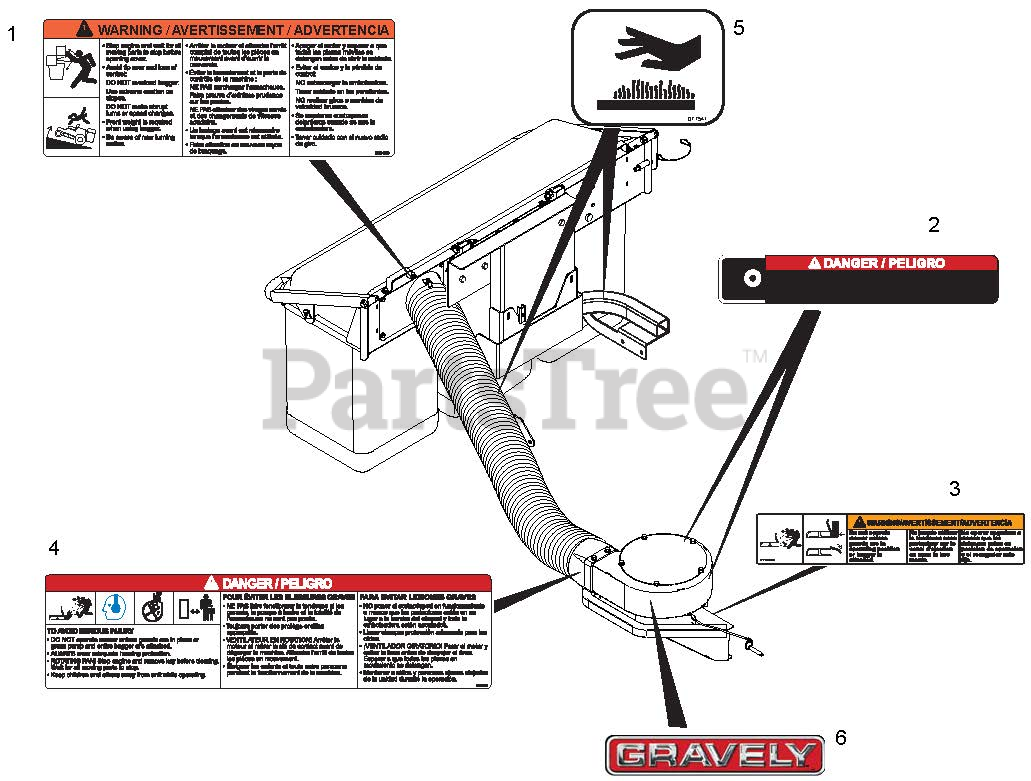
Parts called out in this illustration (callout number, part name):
1	Decal – Warning, Bagger Cover
2	Decal, Danger
3	Decal, Warning
4	Decal – Caution, Grass Pump
5	Decal, Hot Surface
6	Decal, Gravely
